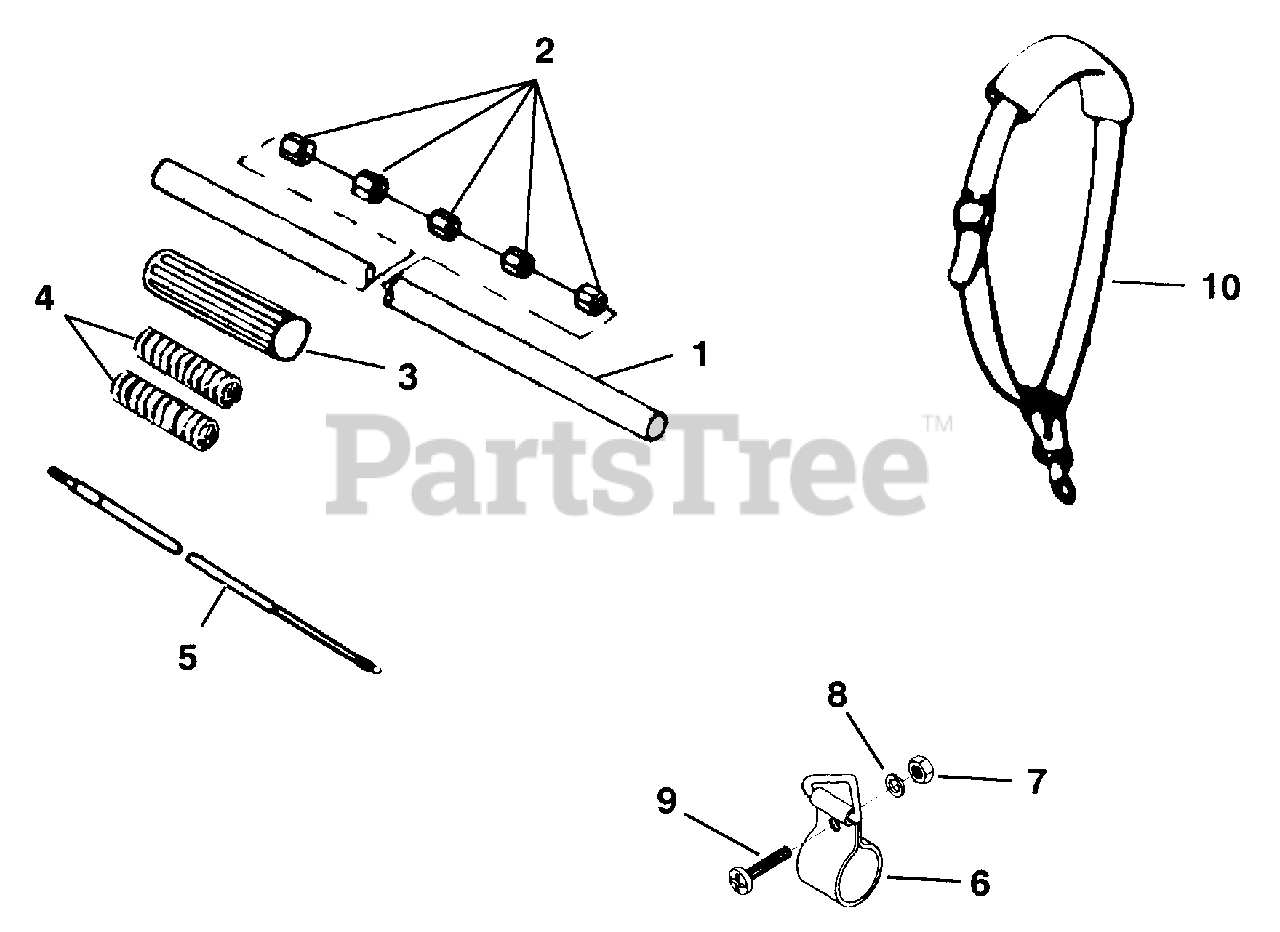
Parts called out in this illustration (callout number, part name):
1	Driveshaft Tube Assembly
5	Driveshaft
6	Hanger Assembly
7	Nut
